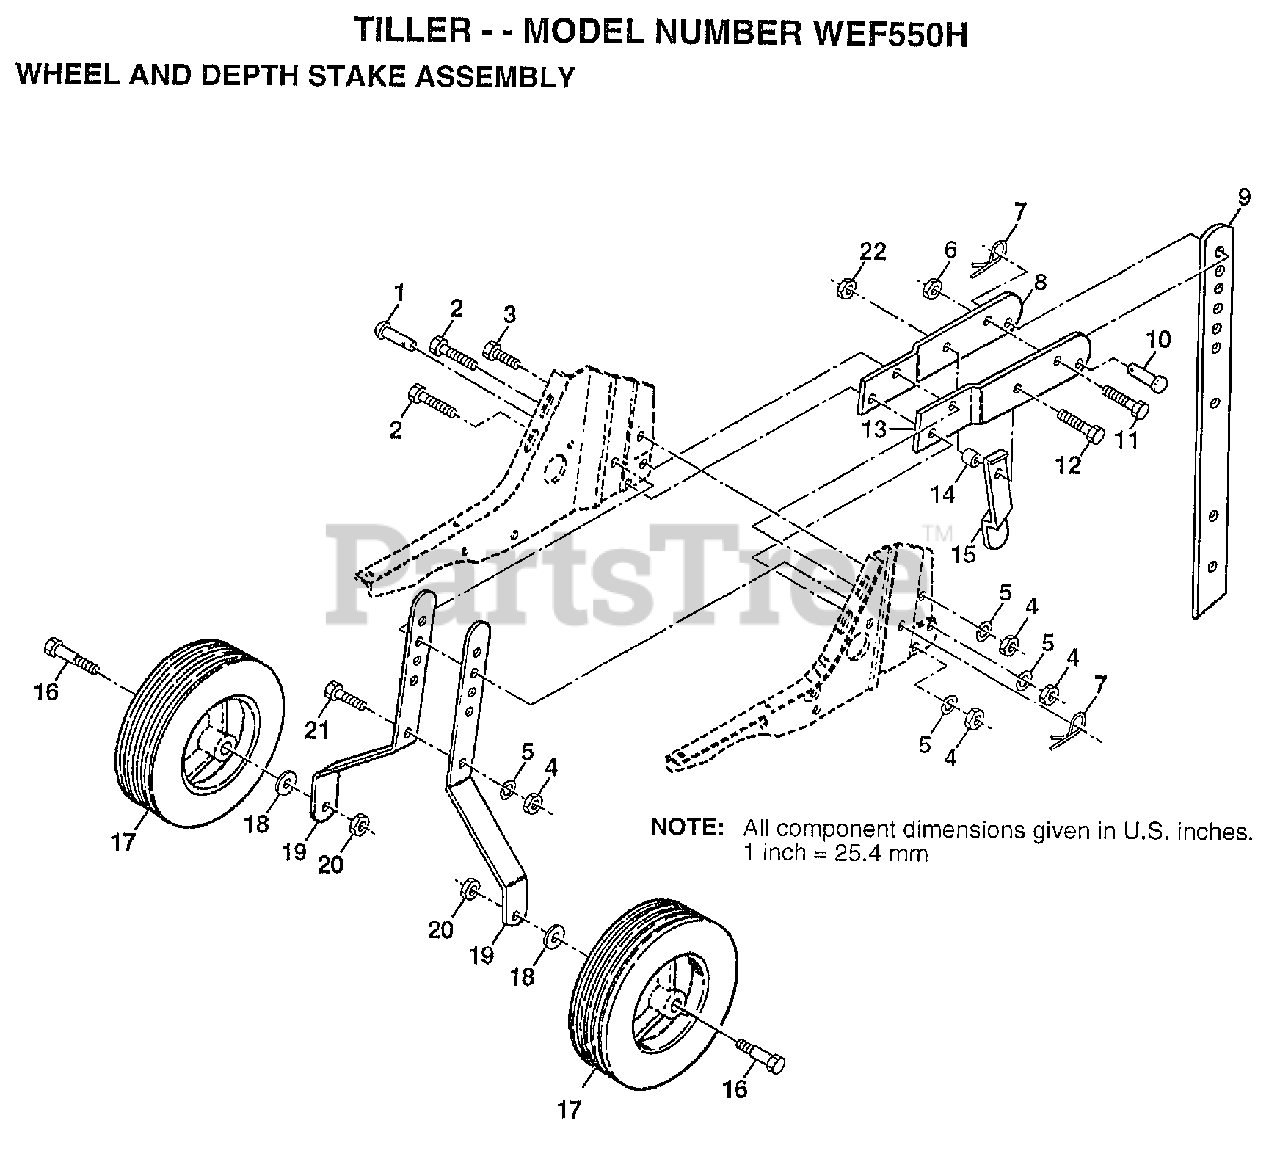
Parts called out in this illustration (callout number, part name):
1	DRILLED RIVET RT
3	BOLT
4	NUT.HEX.5/16-18
5	LOCKWASHER
6	NUT
11	BOLT
12	BOLT.HEX.5/16-1.5
14	WASHER
15	STAKE SPRING TI
16	BOLT SHOULDER
18	WASHER
22	NUT
